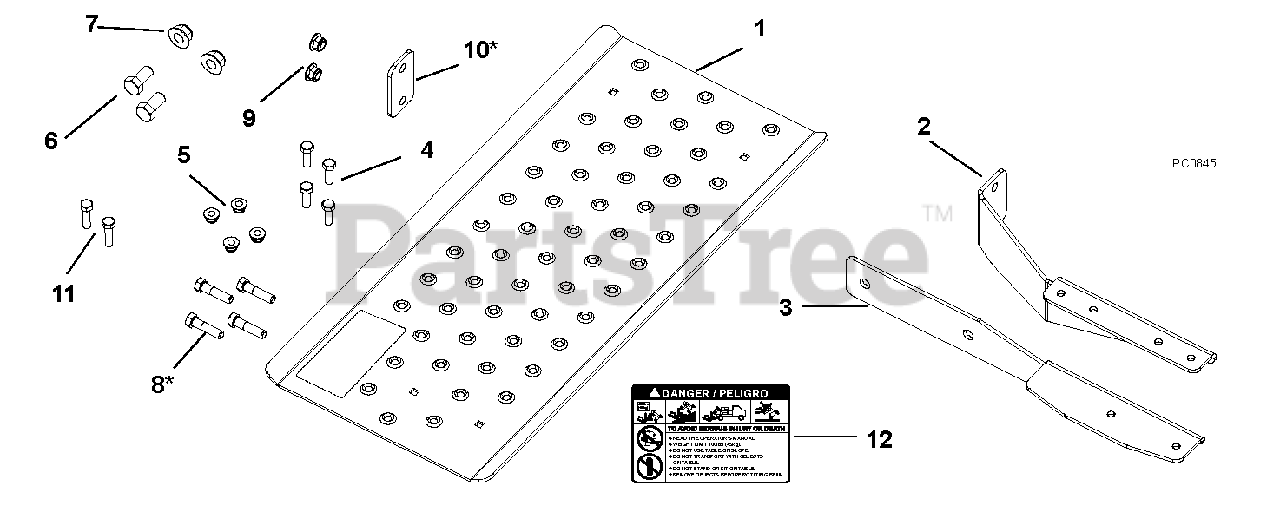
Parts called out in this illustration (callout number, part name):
1	Bracket, Work Table
2	Bracket, Rear Table Mount
3	Bracket, Front Table Mount
4	Bolt, Round Head Square Neck .312-18 x 1
5	Nut, Nyloc Flange .312-18
6	Bolt, Hex .50-13 x 1
7	Nut, Locking Top Flange .50-13
8	Bolt, Hex .38-16 x 1.5
9	Nut, Locking Top Flange .38-16
10	Spacer Plate, Work Table
11	Bolt, Hex .38-16 x 1.25
12	Decal, Work Table
